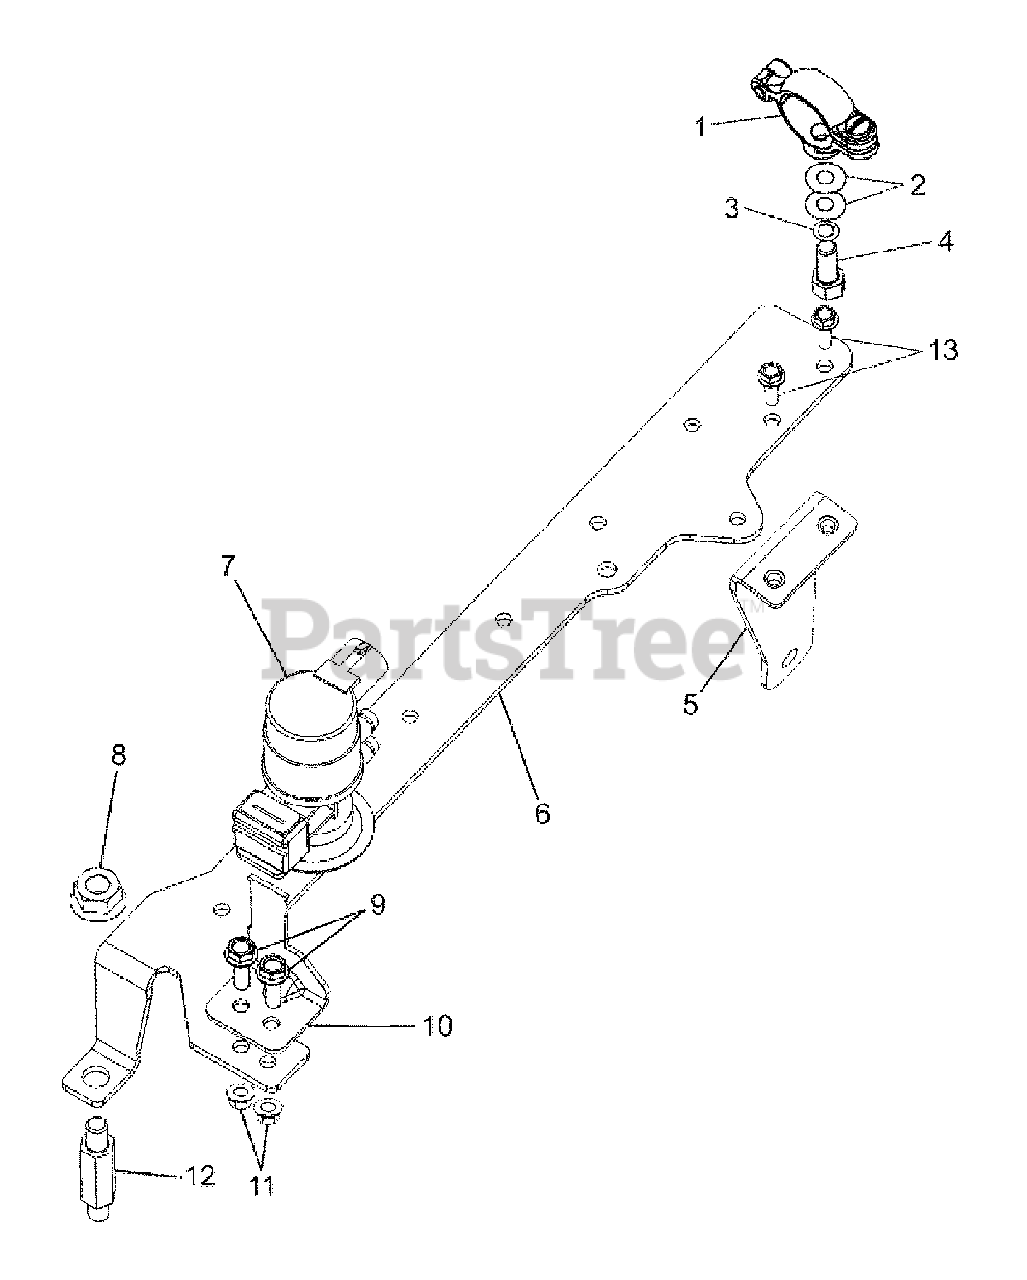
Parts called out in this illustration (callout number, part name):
1	CLAMP
2	WASHER
3	WASHER, Lock
4	BOLT
5	BRACKET
6	BRACKET
7	VALVE, Regulator
8	NUT
9	SCREW
10	BRACKET
11	NUT
12	STUD
13	BOLT
